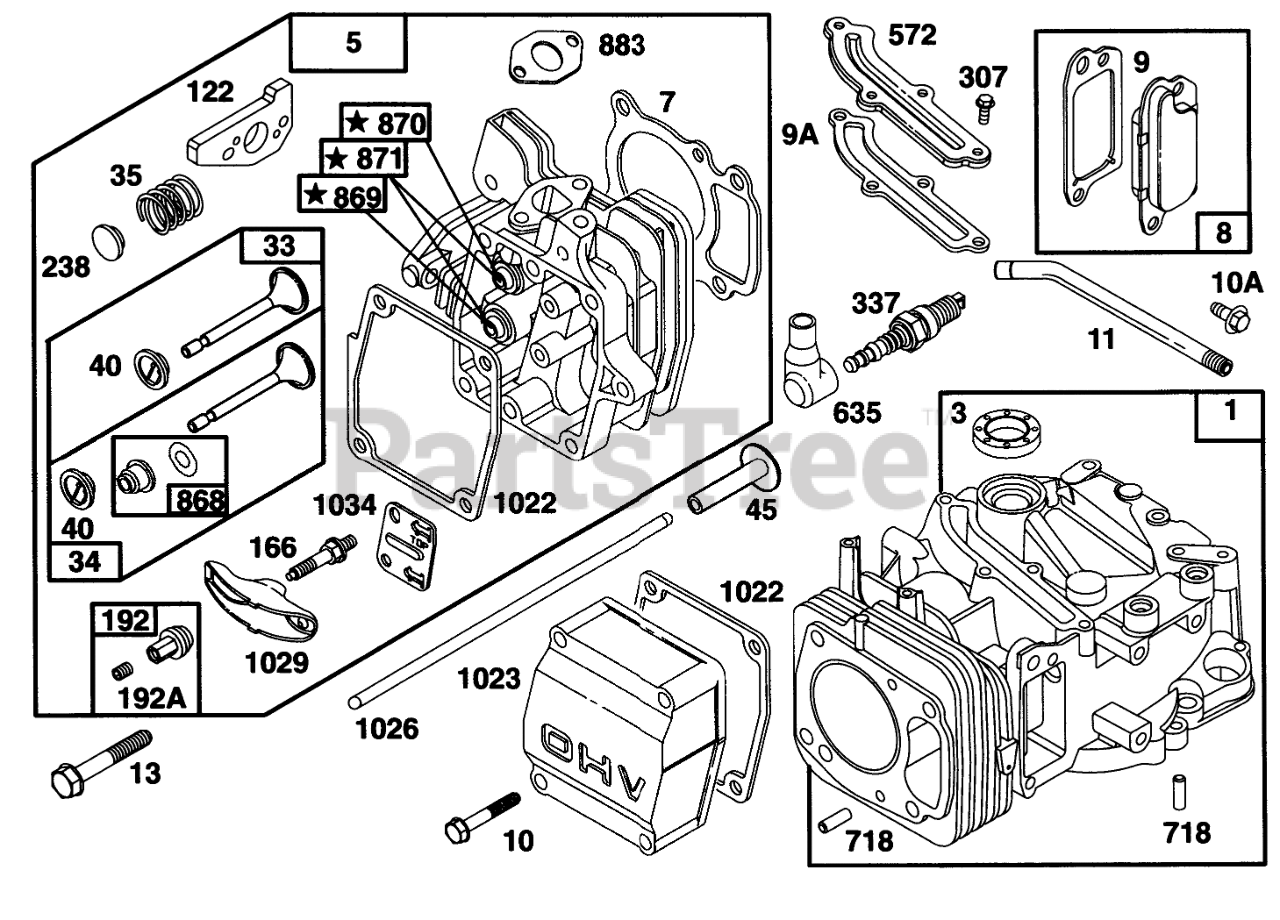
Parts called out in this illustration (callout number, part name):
1	CYLINDER ASSEMBLY
3	SEAL - OIL
5	CYLINDER HEAD
7	CYLINDER HEAD GASKET
8	Breather Assy
9	BREATHER GASKET
9A	GASKET-BREATHER
10	HEX HEAD SCREW
10A	HEX HEAD SCREW
11	TUBE - BREATHER
13	SCREW - CYLINDER HEAD
33	EXHAUST VALVE
34	INTAKE VALVE
35	VALVE SPRING
40	SPRING RETAINER
45	VALVE TAPPET
122	ADAPTER ASSEMBLY
166	ROCKER ARM STUD
192	NUT - HEX SPECIAL
192A	SCREW SET
238	VALVE CAP
307	SCREW - SEM
337	PLUG-SPARK
572	BAFFLE - CYCLINDER
635	SPARK PLUG ELBOW
718	DOWEL - SLEEVE
868	ASM - VALVE SEAL
869	Seat-Valve (Intake)
870	Seat-Valve (Exhaust)
871	Bushing-Guide
883	EXHAUST GASKET
1022	ROCKER COVER GASKET
1023	COVER - VALVE
1026	PUSH ROD
1029	ROCKER ARM
1034	PUSH ROD GUIDE
